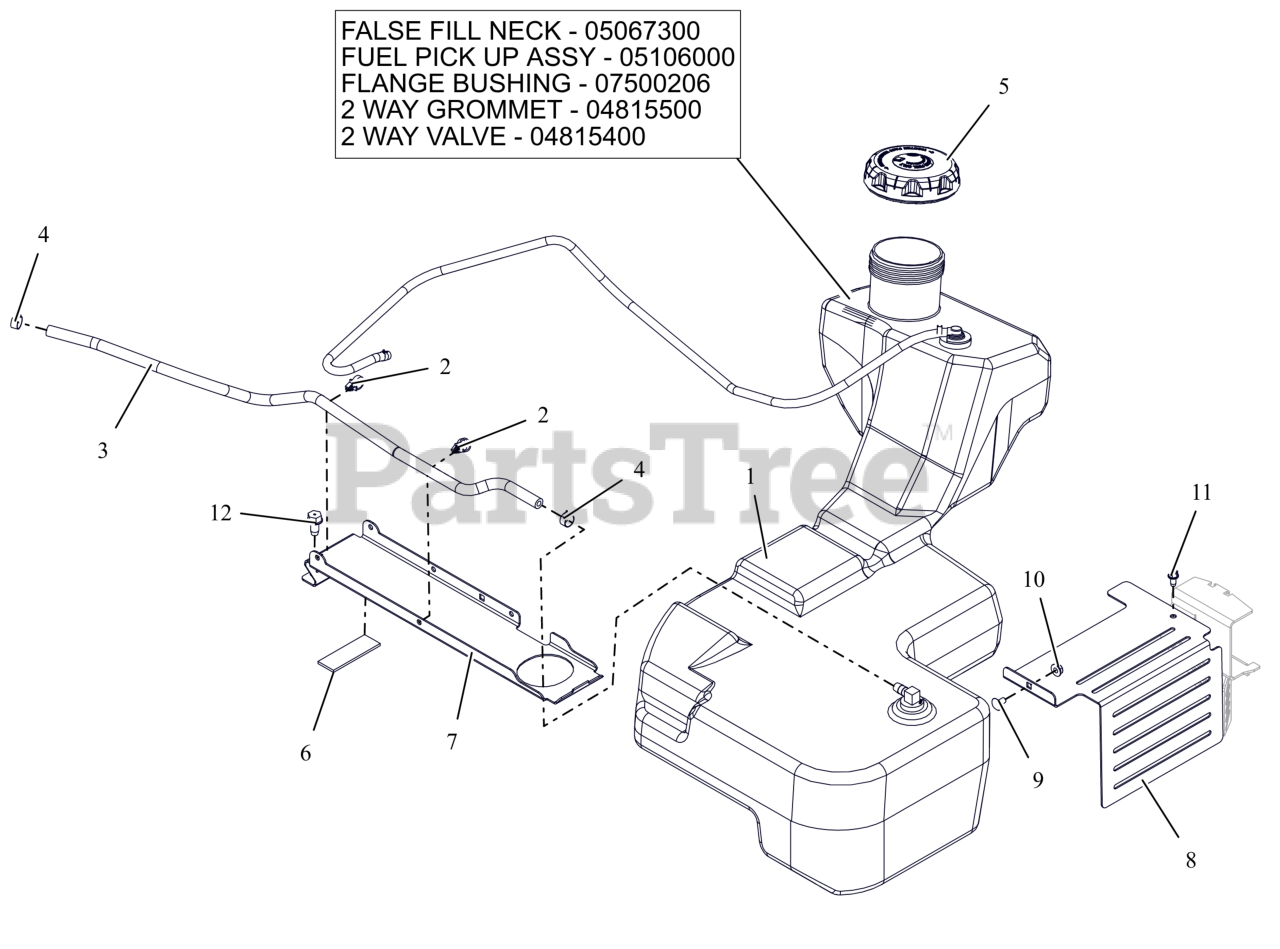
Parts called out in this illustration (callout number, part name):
1	ASM, FUEL TANK-HD
1	ASM, HD FUEL PICK-UP
1	BSHG-FLG .375X1.062X.625 NITR
1	GROMMET, 2-WAY
1	VALVE, 2-WAY
2	ROUTING CLIP (1/2" ID)
3	HOSE, .25 LOW-PERM BULK GAS
4	CLAMP, FUEL LINE
5	CAP, FUEL VENTIN AUTOLOCK
6	PAD,RBR 1.0"X3.0" W/ADHESIVE
7	BRKT, FUEL TANK HOLD DOWN
8	GUARD, TRANSAXLE FAN LH (BLACK)
9	BLT, RHSSN.25-20X.500 G5 ZCC
10	NUT-LK-CTR-FLG .25-20 ZC120
11	SCR-TAP .25-20X.50 HWH ZCC
12	SCR,TAP .375-16X.75 HWH TR ZCC
